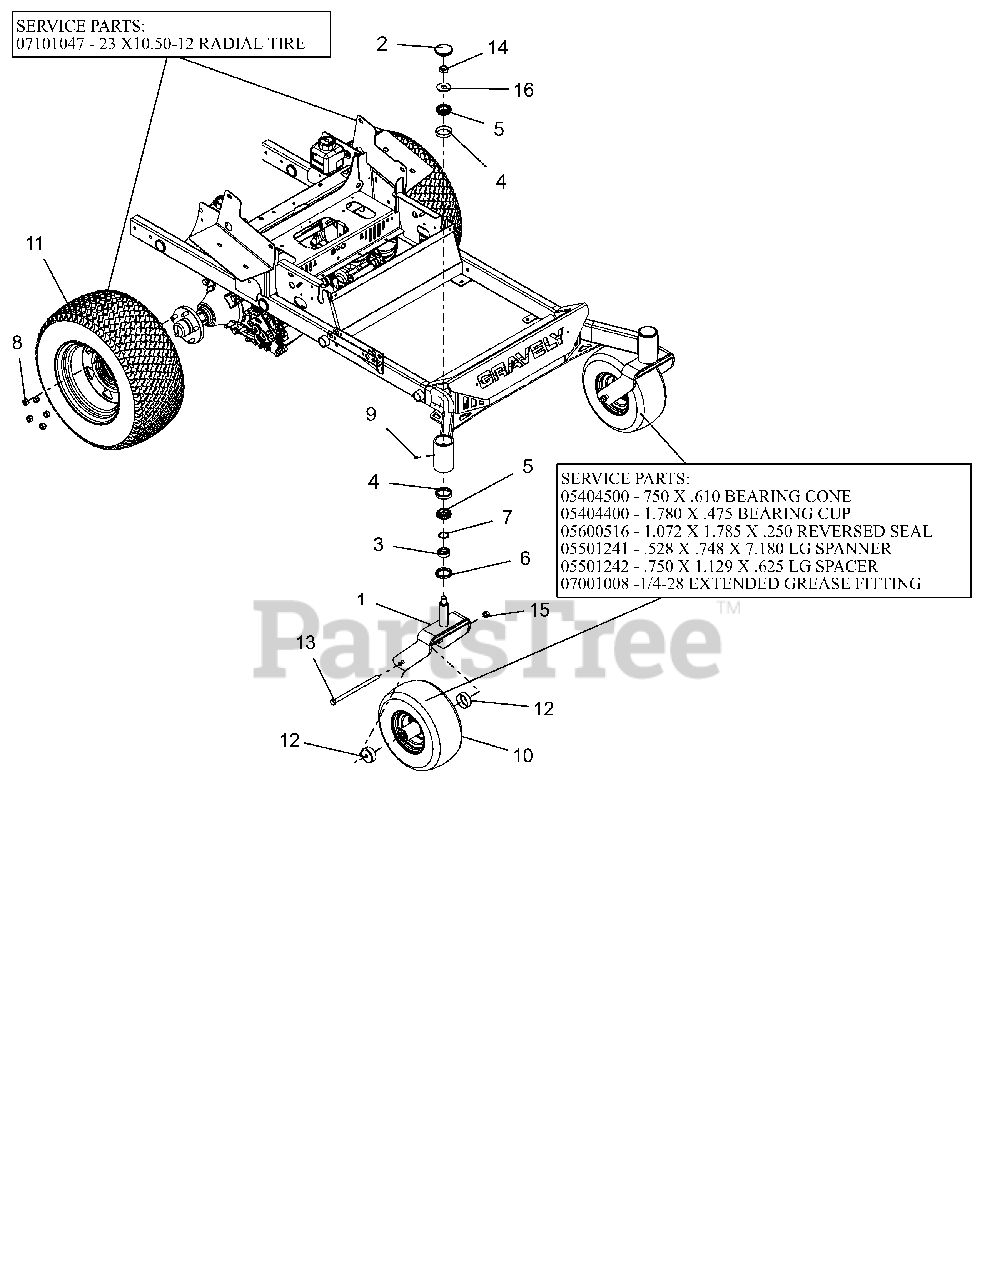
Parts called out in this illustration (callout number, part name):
1	CASTER FORK WMT - RED
2	CAP, DUST
3	SPCR, FRONT CASTER FORK
4	BRG-CUP 2.328X.465
5	BRG-CONE 1.25X.66
6	SEAL, OIL 1.75 X 2.332 X .312
8	WHEEL NUT .500-20 YZ
9	FTG, .25-28 FLUSH MNT GREASE
10	ASM, WHL/TIRE 15X6.00-6 SEMI
10	BRG-CONE .750X.61
10	BRG-CUP 1.781X.475
10	SEAL,1.072X1.785X.250 REVERSED
10	SPANNER, .528X.748X7.18 LG
10	SPACER, .750X1.129X.625 LG
10	GREASE FITTING 1/4-28 EXTENDED
11	ASM,WHL/TIRE 23X10.50-12RADIAL
11	TIRE, 23 X 10.50-12 RADIAL
12	SHIELD, WHEEL BEARING
13	@BLT-HEX .50-13X9.00 GR5 YWZC
14	NUT-JAM TOPLK .75-16 YWZC
15	@NUT-LK-TOP-FLG .50-13 YWZC
16	@WSHR-FL-STL.812X2.00X.148YWZC
